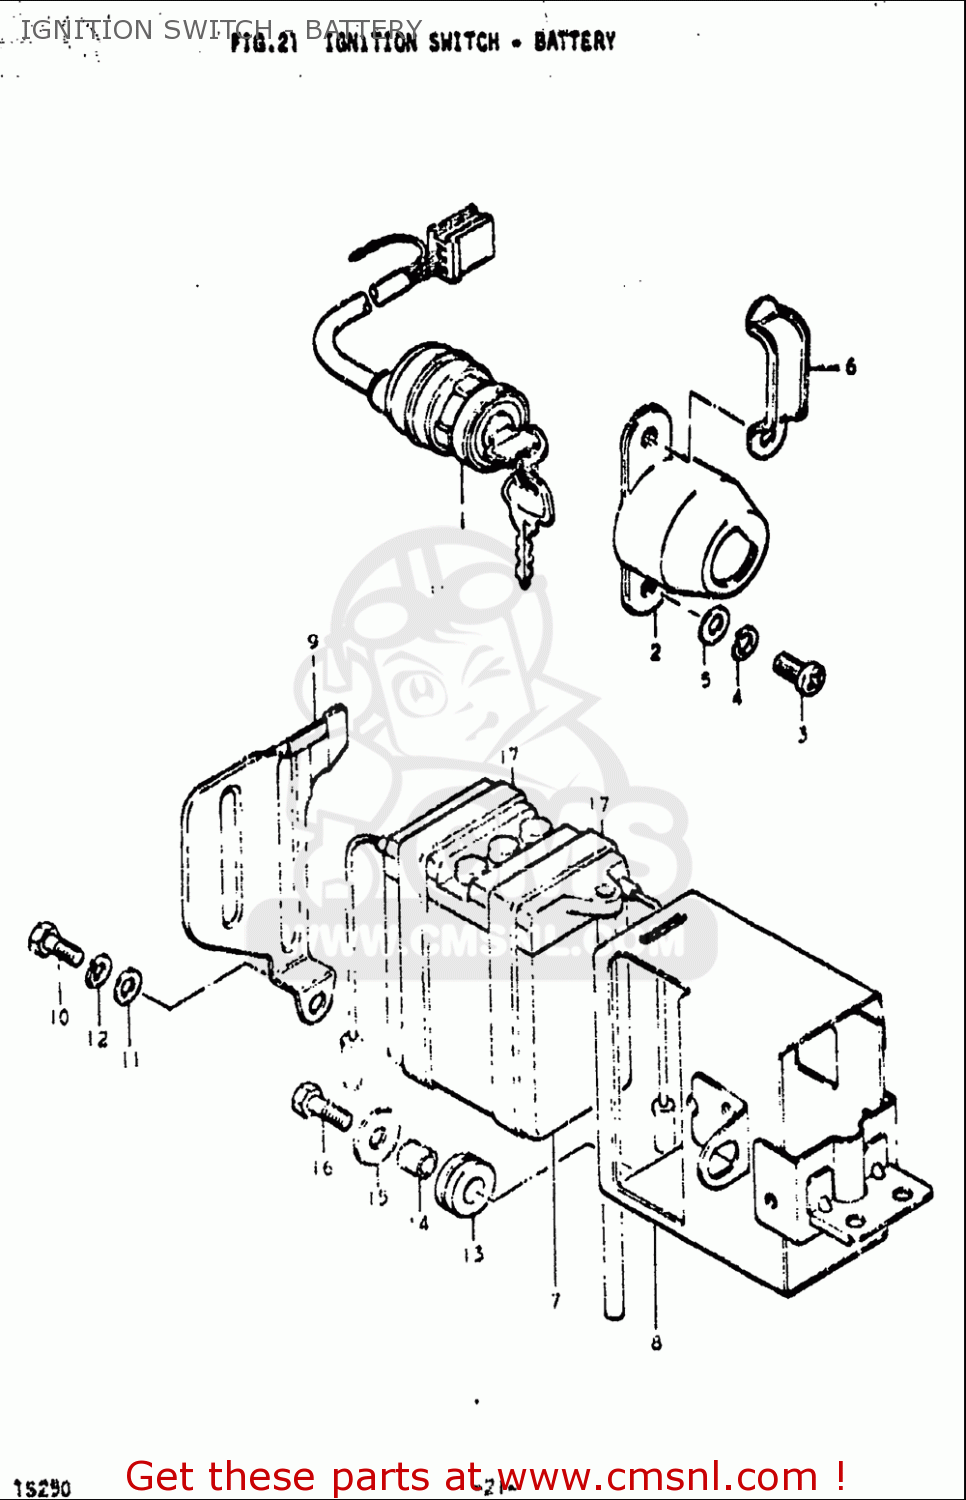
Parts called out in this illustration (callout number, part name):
3	SCREW
4	WASHER,LOCK
5	WASHER
6	CLAMP
7	BATTERY ASSEMBLY (6V)
10	SCREW(6X10)
11	WASHER
12	WASHER,LOCK
13	CUSHION
14	SPACER,6.5X9X7
15	WASHER(6.5X20X1.2)
16	SCREW
17	PROTECTOR,BATTERY
